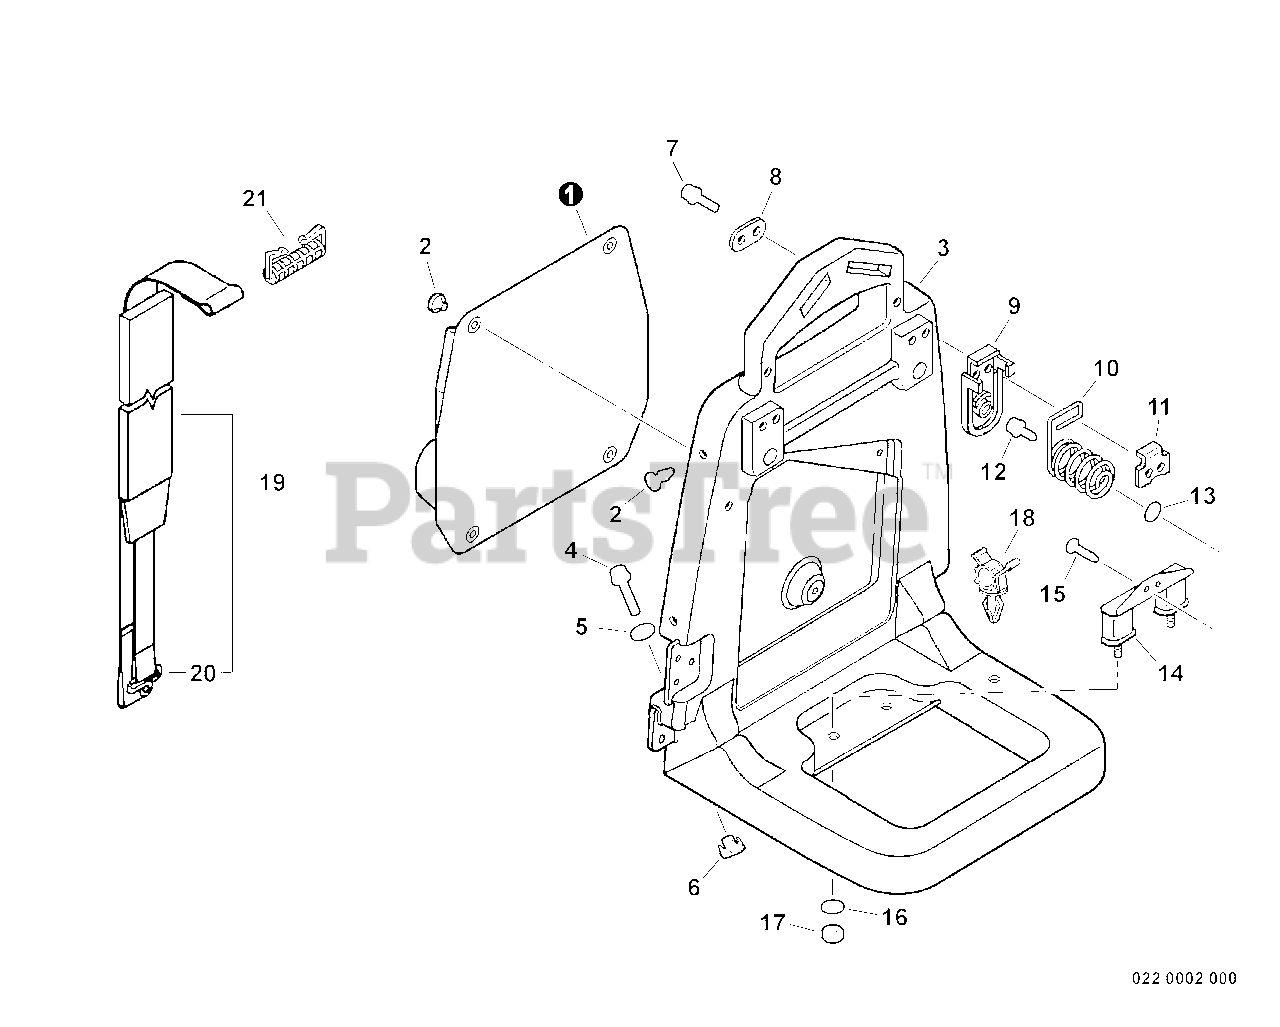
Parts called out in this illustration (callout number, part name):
1	CUSHION, BACKPACK
3	FRAME, BACKPACK
4	BOLT 6×25
5	WASHER 6.6×20×1.6
7	BOLT 5×20
8	PLATE, EYE
9	HOLDER, SPRING
10	SPRING, COMPRESSION
11	PLATE, THREADED
12	BOLT 5×20
13	WASHER 5.5×16×2T
14	CUSHION 5
15	SCREW 5×16
16	WASHER 5.5×18×1
17	NUT, FLANGE M5
18	CLIP, CABLE
19	HARNESS ASSY, BACKPACK
20	RING, HARNESS
21	CLIP, HARNESS
